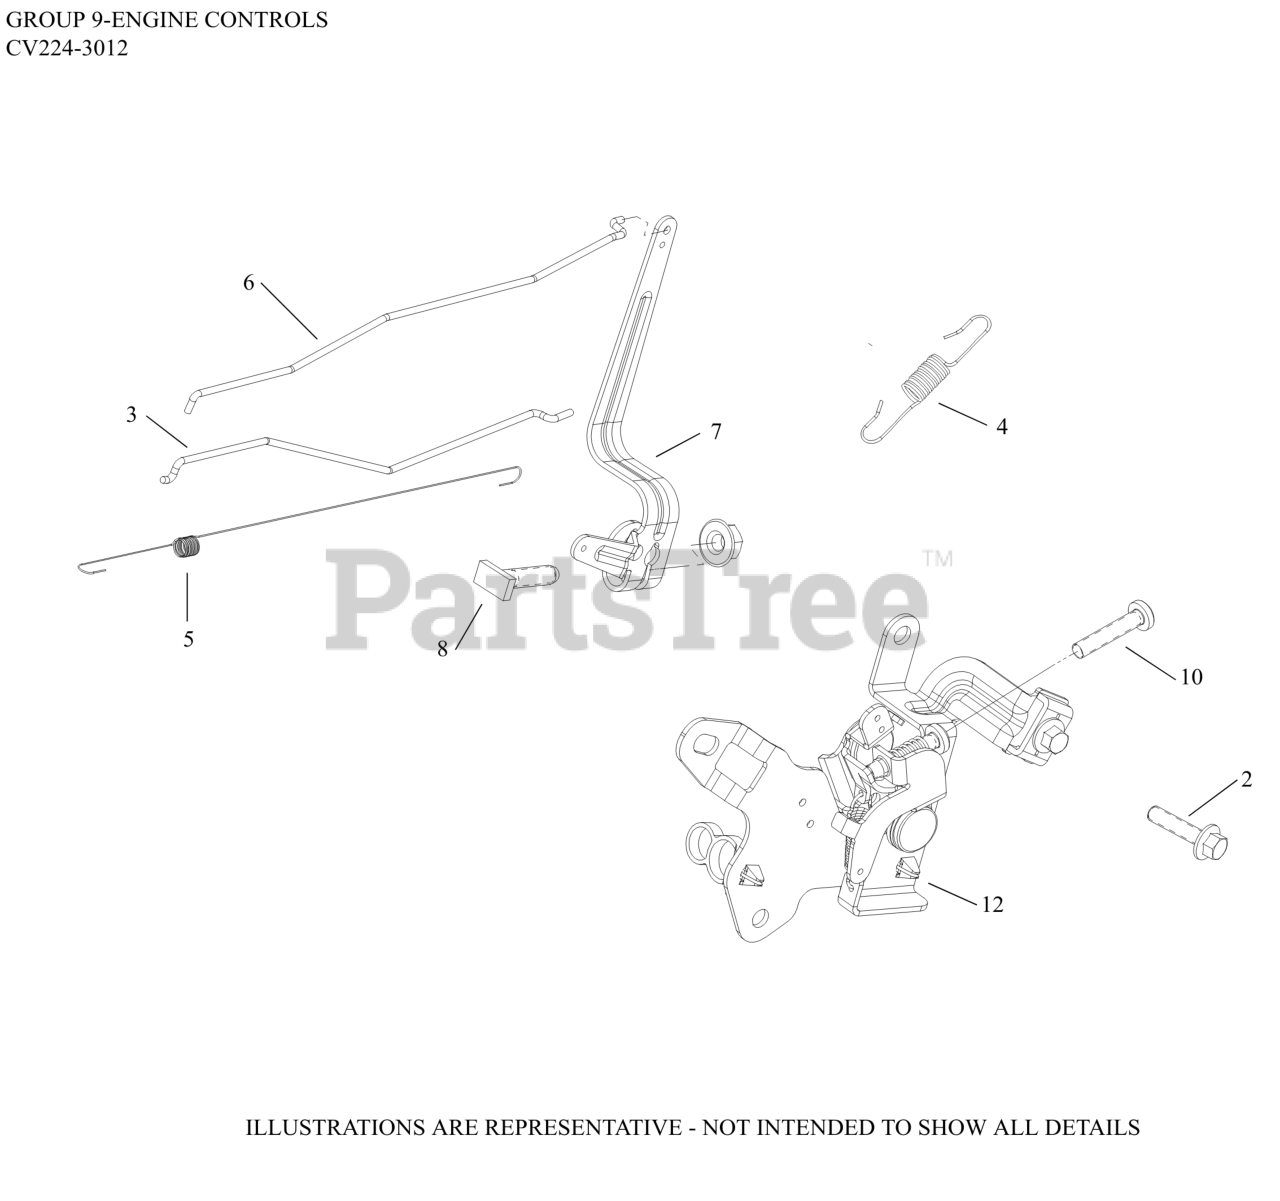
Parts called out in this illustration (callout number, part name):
2	SCREW, (M5) HEX FLANGE
3	LINKAGE, CHOKE
4	SPRING, GOVERNOR
5	SPRING, LINKAGE
6	LINKAGE, GOVERNOR
7	LEVER, GOVERNOR
8	SCREW, RECTANGLE HEAD (M6)
10	SCREW, SPEED ADJUSTING
12	CONTROL ASSEMBLY, VARIABLE SPEED-NO KILL
